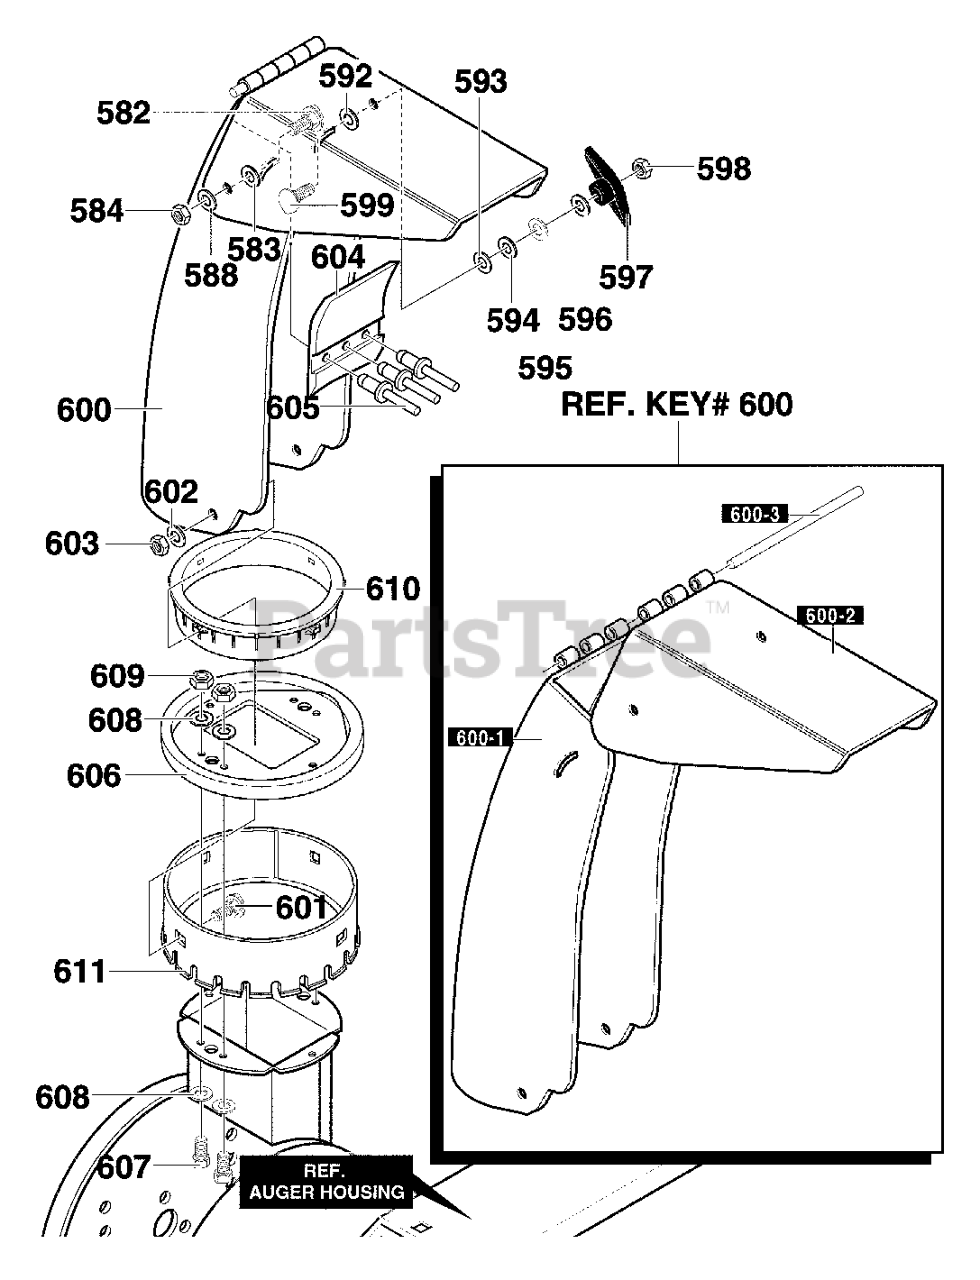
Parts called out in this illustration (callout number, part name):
582	BOLT, 5/16-18 X.75
583	WASHER , PLASTIC
584	NUT, 5/16-18
588	WASHER, PLASTIC
592	WASHER, PLASTIC
593	WASHER, PLASTIC
594	FLATWASHER .349X.69X.066
595	WASHER, SPLITLOCK
596	FLATWASHER .349X.69X.066
597	KNOB, T 2/BLADE W/NUT
598	NUT, 5/16-18 REGHEX
599	CARR. BOLT, 5/16-18X1.00
600-1	CHUTE, LOWER
600-2	CHUTE, UPPER
601	BOLT, 5/16-18 X1.00
602	WASHER, FLAT .349 X.69 X.066
603	NUT, 5/16-18 HEXNYL
604	FLAP, CHUTE
605	POP, RIVET
606	CHUTE COLLAR
607	SCREW, 1/4-20X.75
608	WASHER, FLAT .281X.63X.065
609	NUT, 1/4-20 HEX NYLOCK
610	RETAINER, RING INNER
611	RETAINER, RING OUTER
